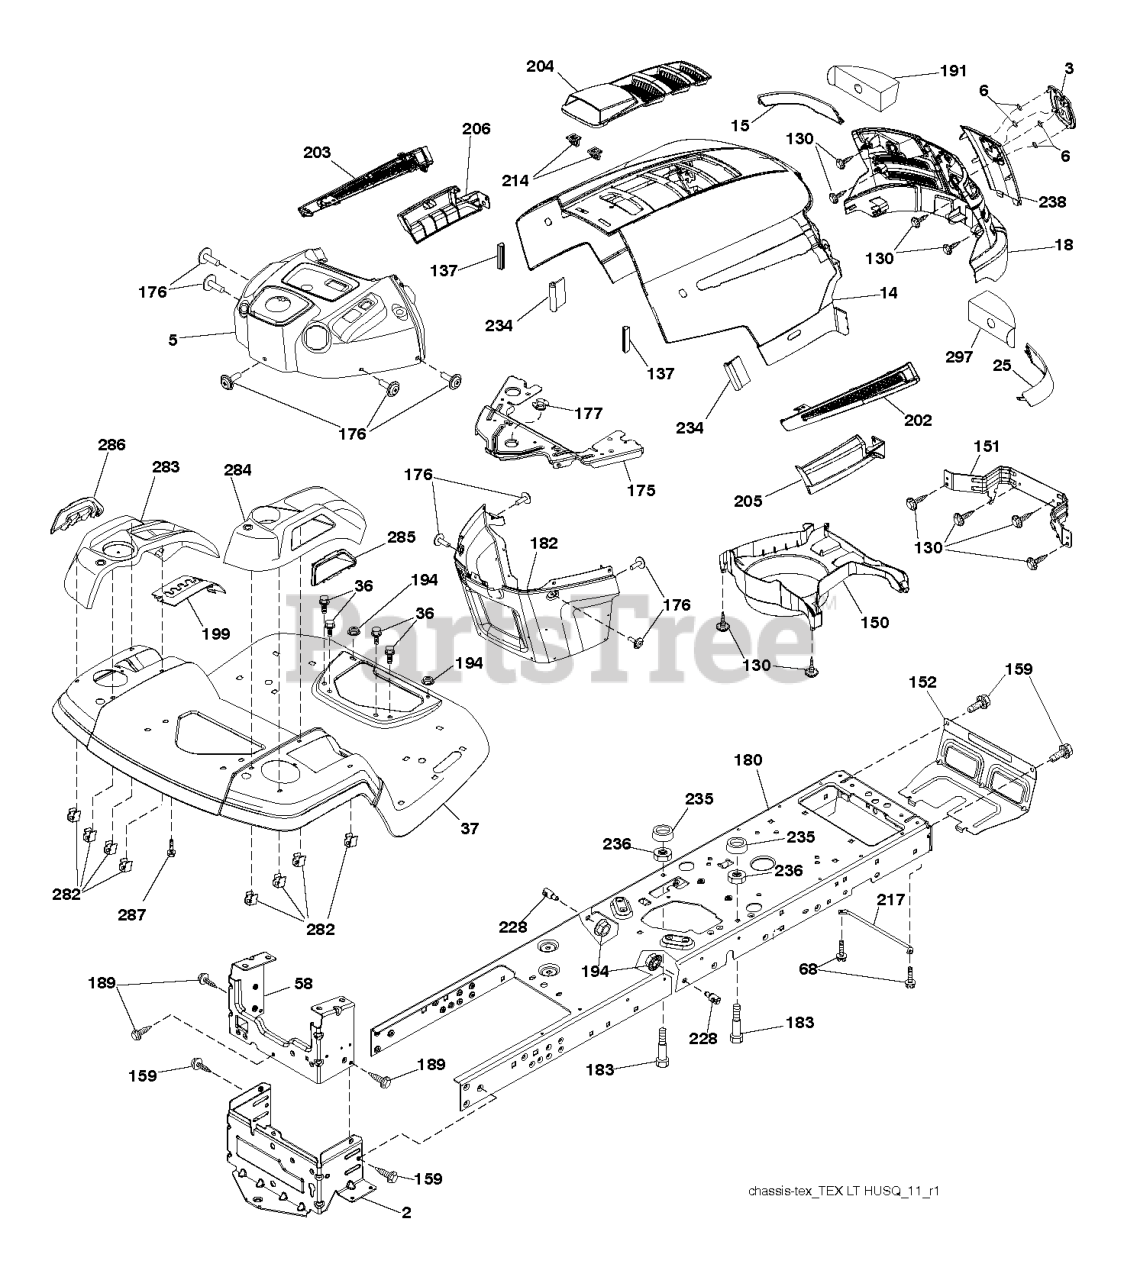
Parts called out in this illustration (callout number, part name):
2	DRAWBAR.LOWER.2PC.18/22
3	RP LOGO
5	DASH
14	HOOD
15	LENS.HUSQVARNA LT.LH
18	RP GRILLE/LENS ASM.
25	LENS.HUSQVARNA LT.RH
36	SCREW 5/16"
37	RP FENDER.TLT.FS.W/CPH.422
58	DRAWBAR UPPER 2PC SMALL FENDER
68	Screw 5/16-18 x 1/2 Hex, Self Tapping 5/16-18 x 1/2
130	SCREW.#10 X 0.750.BOS
137	BUMPER DASH
151	BRACKET PIVOT
152	SHIELD.BROWNING/DEBRIS
159	SCREW, 3/8-16X3/4
162	SCREW.HI-LO.CONSOLE
175	CROSSMEMBER
176	SCREW.#10-24X5/8.RN.QU
177	BUSHING STEERING
180	CHASSIS.STAMPING.LT/GT
182	DASH.LOWER.PREDATOR LT
183	BOLT.5/16-18X1-1/4 FULL.THREAD
189	SCREW
191	INSERT.REFLECTIVE.RH.
194	NUT LOCK HEX FLANGE 5/16-18
195	PLUG DASH
199	PLATE.DECK.LIFT.HUSQ.LT
202	VENT SIDE HOOD RH
203	VENT SIDE HOOD LH
204	VENT TOP HOOD
205	SKIRT SIDE RH
206	SKIRT SIDE LH
214	CLIP.RETAINER.TINNER.
217	ROD.PIVOT.HOOD
228	STUD.FASTNER.W/ANTI-ROTATE
234	BUMPER.HOOD.TEX.HUSQVARNA
235	SPACER FENDER
236	NUT.CENTERLOCK.5/16-
238	TRIM
282	CLIP.RETAINER.CONSOLE.LT.HUSQ
283	CONSOLE.DECK.LIFT.HUSQ.N/FR.GR
285	CONSOLE INSERT RH
286	CONSOLE.INSRT.LH.HUSQ.LT.BLACK
287	SCREW 1/4X20
297	INSERT REFLECTIVE
